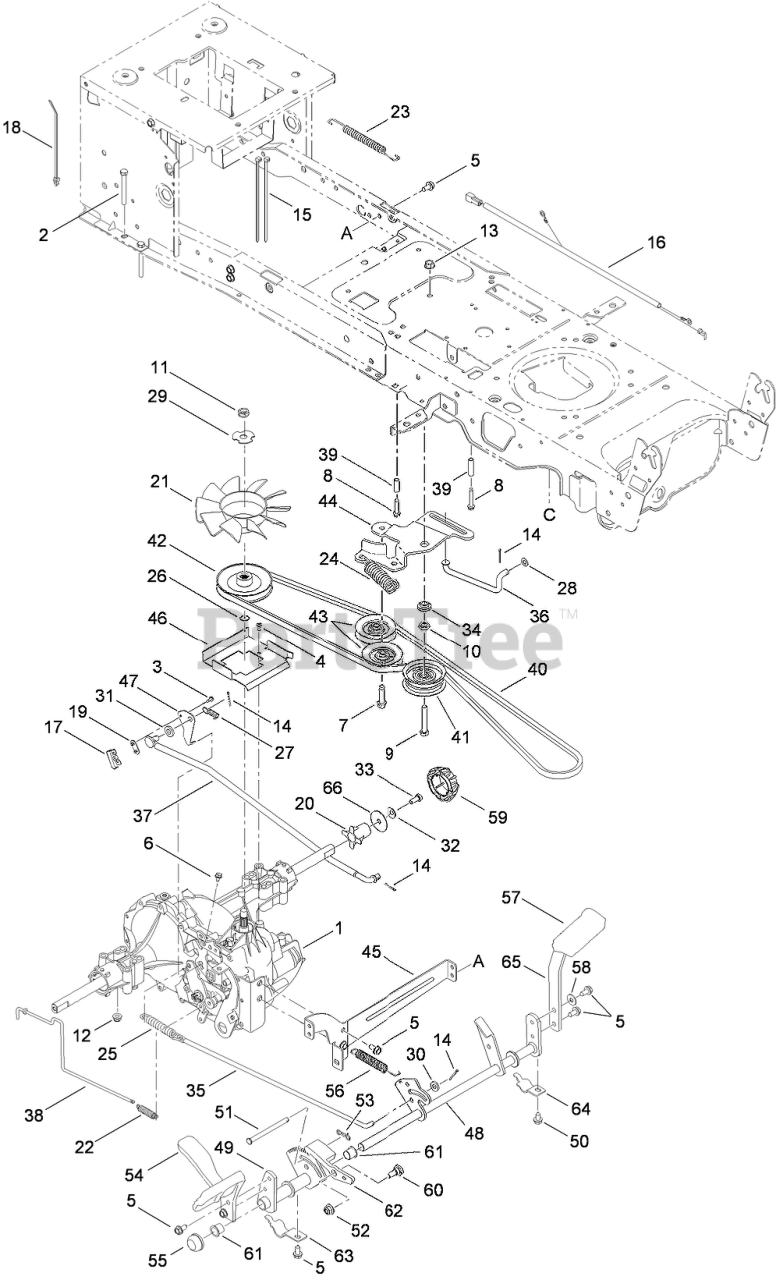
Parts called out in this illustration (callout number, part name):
1	HYDRO TRANSMISSION ASM
2	SCREW-HEX
3	SCREW-HWHTF
5	SCREW-TAP
6	SCREW-TAP
7	SCREW-TAP
8	SCREW-TAP
9	SCREW-HH
10	NUT-JAM
11	NUT-JAM
12	NUT-LOCK, FLANGE
13	NUT-LOCK, FLANGE
14	PIN-COTTER
15	TIE-CABLE
16	HARNESS-JUMPER
17	SWITCH-SPRING, SHORT
18	TIE-CABLE
19	PLATE-INSULATOR
20	SLEEVE
22	SPRING-EXTENSION
23	SPRING-EXTENSION
24	SPRING-EXTENSION
25	SPRING-EXTENSION
26	RING-WIRE
27	SPRING-EXTENSION
28	WASHER-FLAT
29	WASHER-LOCK
30	WASHER-FLAT
31	WASHER-FLAT
32	WASHER-BELL
33	SCREW-HH
34	SPACER-SHOULDER
35	ROD-BRAKE
36	ROD-BYPASS, FOOT PEDAL
37	ROD-CONTROL
38	ROD-BYPASS, HYDRO
39	SPACER
40	BELT-V
41	PULLEY-IDLER, FLAT
42	PULLEY-INPUT
43	PULLEY-IDLER, Y TYPE
44	BRACKET-IDLER, CENTER DOUBLE
45	BRACKET-MOUNTING
46	BRACKET-SUPPORT, BELT DISENGAGE
47	BRACKET-ACTUATOR
48	BRAKE CONTROL ASM
49	BRACKET-PEDAL
50	SCREW-HWH
51	PIN-CLEVIS
52	NUT-LOCK, FLANGE
53	PIN-COTTER
54	PEDAL-CONTROL
55	CAP-PUSH
56	SPRING-EXTENSION
57	PAD-PEDAL, BRAKE
58	WASHER-BELL
59	CAP-HUB
60	BOLT-SHOULDER
61	BEARING-FLANGE
62	LATCH-CRUISE
63	BRACKET-STRAP, PEDAL SUPPORT
64	BRACKET-STRAP, PEDAL SUPPORT
65	BRACKET-PEDAL, BRAKE
66	WASHER-FLAT
